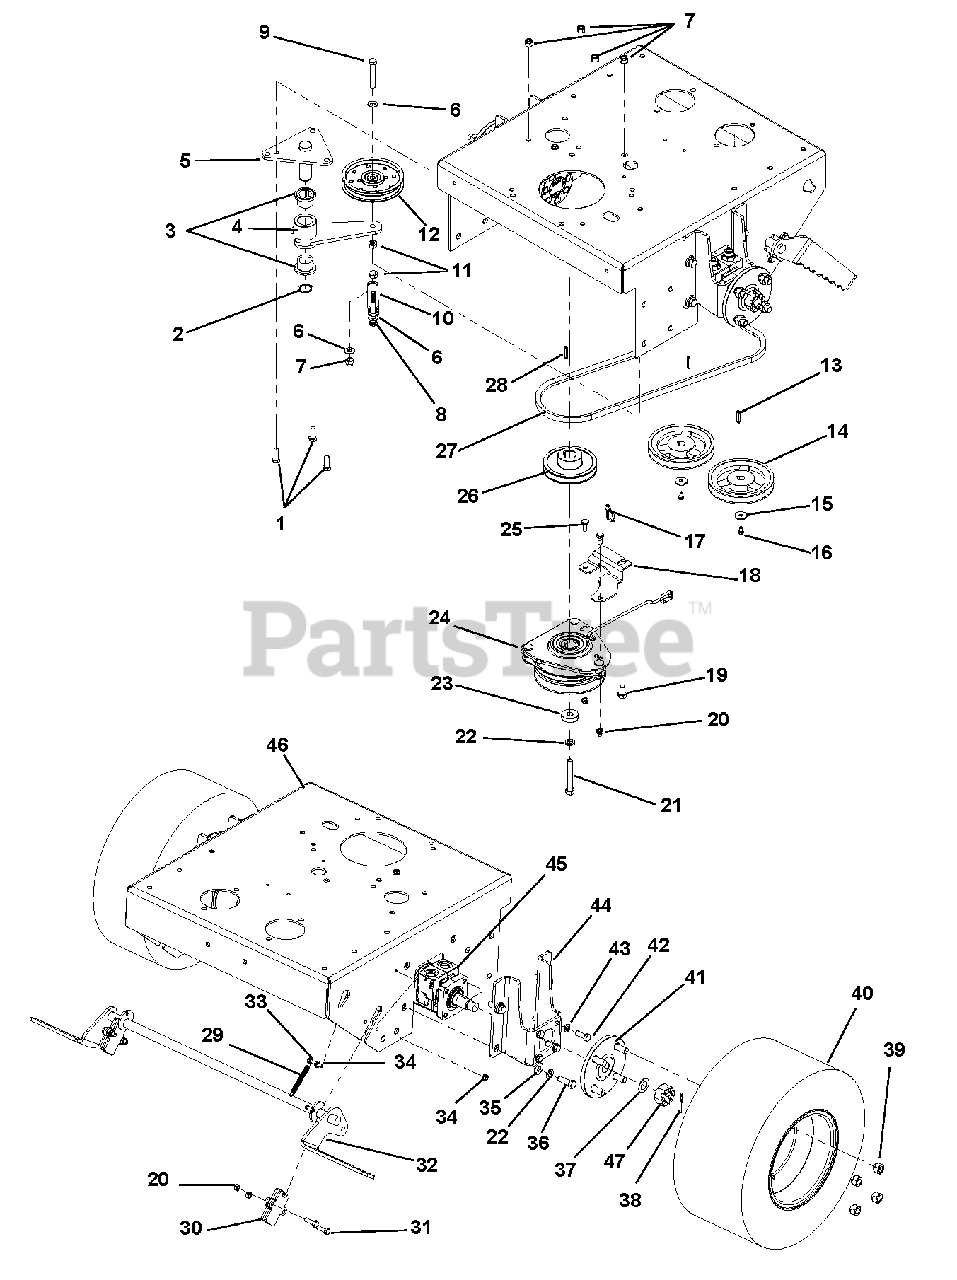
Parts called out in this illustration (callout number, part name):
1	BOLT-HEX .38-16 1.00 GR5
2	SNAP RING, 1.00 X .042 EXT
3	BRG, FLG 1.00 X 1.25 X 1.00
4	WLDT, IDLER ARM
5	WLDT, IDLER PIVOT MOUNT
6	WASHER, .406 X .813 X .065 FLAT Y
7	LOCKNUT, 3/8-16 NYLOC Y
8	BOLT, 3/8-16 X 3.00 HEX 8 Y
9	BOLT, .38-16 X 2.50 HEX 5 Y
10	SPRING, EXT .900X.135X4.50 Y
11	LOCKNUT, 3/8-16 WHIZ Y
12	PULLEY, FLAT 4.50 X .375 W/BRG
13	KEY, M5 X M5 X M30 RD
14	ASSY, PUMP PULLEY W/SET SCREW
15	WASHER, .250 WIDE HEAVY FLAT Y
16	BOLT, M6 X 1.00 X 10 HEX 8.8 Y
17	CABLE TIE, .15 X 8.50
18	PLATE, CLUTCH DOG
19	BOLT, 7/16-14 X .750 HEX 5 Y
20	LOCKNUT, 5/16-18 NYLOC Y
21	BOLT, HEX .44-20 X 3.00 G5
22	WASHER, .438 MED SPRG LOCK Y
23	SPACER, .468 X 1.38 X .375 Y
24	CLUTCH ASSY, OGURA
25	BOLT, HEX .31-18 X .75 GR5
26	PULLEY, V-BELT 4.45X1.00 W/KEY
27	BELT, HA 55.1 EL AMD OHR
28	KEY, .250 X .250 X .995 TPR
29	SPRING, EXT .375 X .055 X 2.25 Y
30	SHOE, BRAKE SYSTEM FLOAT WALK
31	BOLT, HEX .31-18 X 1.00 GR5
32	WLDT, BRAKE SYS FLOAT HYDRO
33	BOLT, HEX .25-20 X 1.25 GR5
34	LOCKNUT, 1/4-20 WHIZ Y
35	WASHER, .468X1.00X.125 FLAT Y
36	BOLT, HEX .44-14 X 1.25 GR5
37	BUSHING, MACH .750X1.25X.048 Y
38	PIN, COT .125 X 1.50 EXTP Y
39	NUT, 1/2-20 LUG C
40	ASSY, WHEEL & TIRE - 16X6.5-8
41	ASSY, WHEEL HUB
42	BOLT, 3/8-16 X 1 GR8 BLACK
43	WASHER, .375 MED SPRG LOCK Y
44	2BRKT, MOTOR MOUNT FLWLK
45	MOTOR, HYDRAULIC WHEEL
46	WLDT, ENGINE BED GRAVELY FLWLK
47	NUT, .75 UNF2B HEX SLOT JDS14
